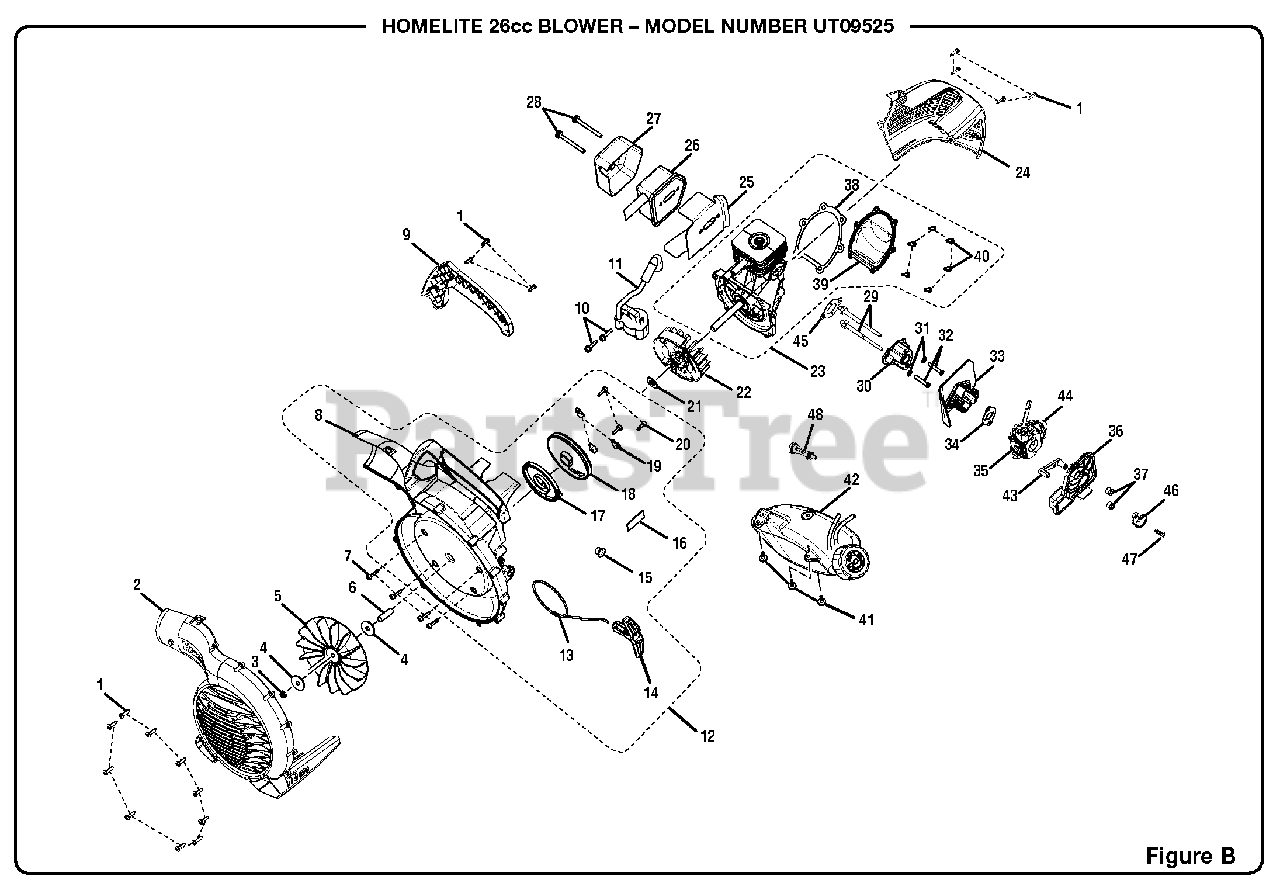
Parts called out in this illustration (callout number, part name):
1	Screw (M4 x 18 mm)
2	Outer Volute
3	Lock Nut (3/8 in.)
5	Fan
7	Screw (M4 x 17 mm, T.F.)
8	Inner Volute
9	Handle Cover
10	Screw (M4 x 19 mm, T.F.)
11	Ignition Module
12	Lower Housing w/Starter Assembly
13	Starter Rope (42 in.)
14	Starter Grip
17	Spring & Container
18	Starter Pulley
19	Pulley Retainer
20	Screw (M4 x 14 mm, T.F.)
21	Washer
22	Rotor and Pawl Assembly
23	Short Block Assembly
24	Engine Cover
25	Muffler Gasket
26	Muffler Assembly
27	Muffler Heat Shield
28	Screw (10-24 x 2-1/8 in.)
29	Screw (10-24 x 2.5 in.)
32	Screw (M5 x 25 mm)
34	Heat Dam Gasket
35	Carburetor
36	Air Box Base
37	Hex Nut (M5)
38	Crankcase Cover Gasket
39	Crankcase Cover
40	Screw (M4 x 12 mm)
41	Screw (M4 x 14 mm)
42	Fuel Tank Assembly w/Cap
43	Choke Lever
44	Primer Bulb
45	Heat Dam Gasket
46	Choke Cover
47	Screw (M4 x 12 mm, T.F.)
48	Fuel Filter
